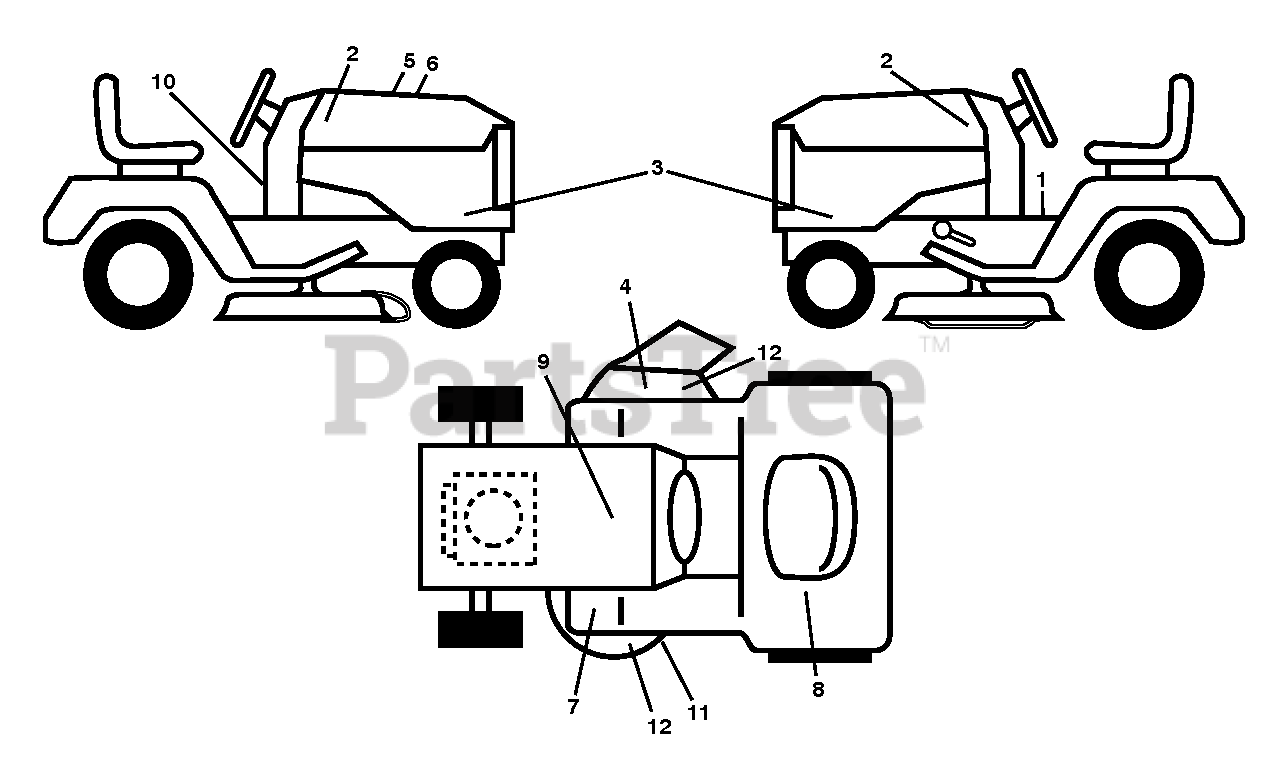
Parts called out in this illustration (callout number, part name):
1	DECAL.FENDER.WARNING
2	RP.DECAL.BADGE.170MM.TEXTLOGO
3	DECAL.SDPL.HUSQGT2.YT.48XLS
4	DECAL, CAUTION
5	DECAL.WARNING.CUST.RESP.E85.
7	DECAL.PEDAL.HUSQ.CROWN
8	DECAL.WARN.RESERVE.FUEL
9	DECAL BTRY SYMBOLS
10	DECAL.HV.REINFORCED.DECKS.2012
11	DECAL.MOWER.SCH.48/54
12	DECAL, NO STEP
